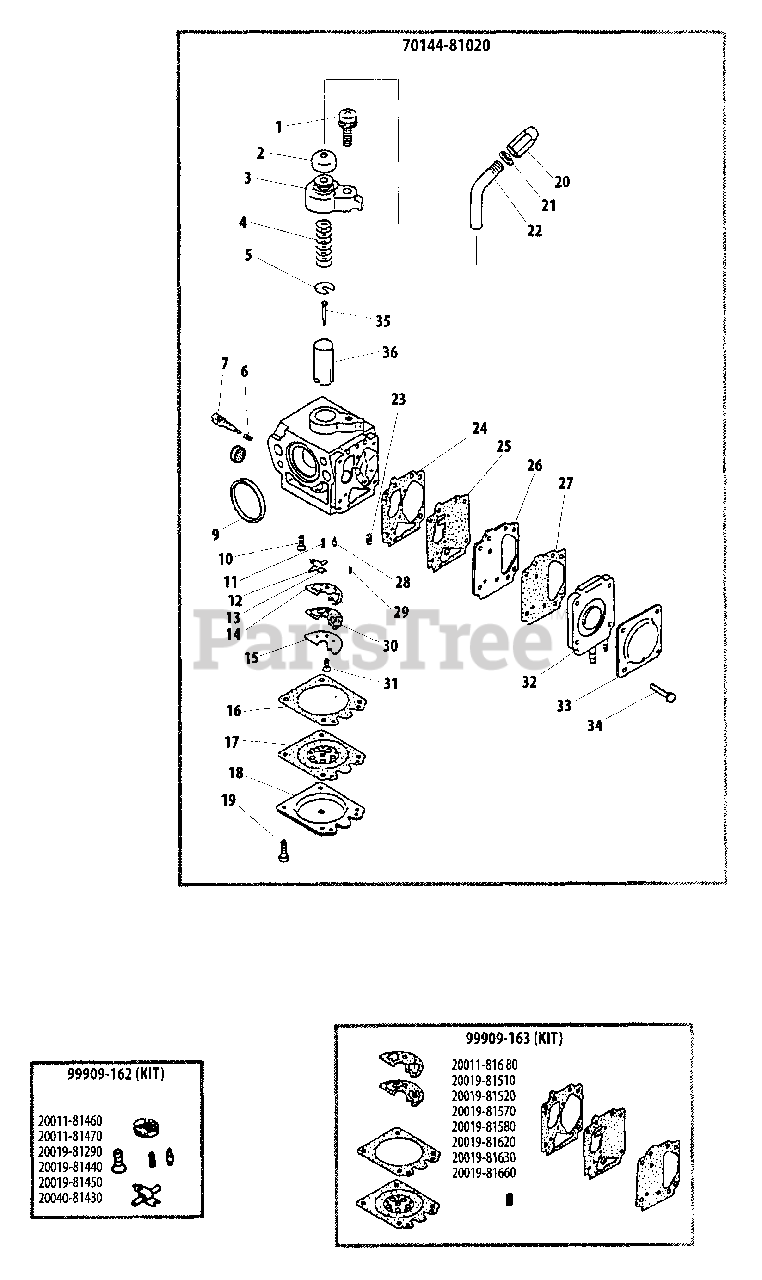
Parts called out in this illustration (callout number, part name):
1	SCREW M5×15
2	CAP, DUST
3	CAP, CARBURETOR
4	SPRING, THROTTLE
5	WASHER, SPRING SUPPORT
6	SPRING
7	SCREW, MAIN ADJUST
9	RING, PACKING
10	SCREW M3×8
11	SPRING
12	PIN, METERING LEVER
13	LEVER, METERING
14	GASKET
15	PLATE
16	GASKET, METERING DIAPHRAGM
17	DIAPHRAGM, METERING
18	COVER, DIAPHRAGM
19	SCREW M3×8
20	ADJUSTER, CABLE
21	NUT, LOCK
22	PIPE, CABLE ADJUSTER(4 pieces ×2 M)
23	SCREEN, FUEL INLET
24	GASKET, PUMP
25	DIAPHRAGM, FUEL PUMP
26	PLATE, PUMP
27	GASKET, FUEL PUMP
28	VALVE, INLET NEEDLE
29	SPRING, COIL
30	VALVE, CHECK
31	SCREW M3×8
32	COVER, PUMP
33	COVER, DIAPHRAGM
34	SCREW M3×14
35	NEEDLE, JET
36	VALVE, THROTTLE
A	CARBURETOR
A	REPAIR KIT
A	DIAPHRAGM/GASKET KIT
